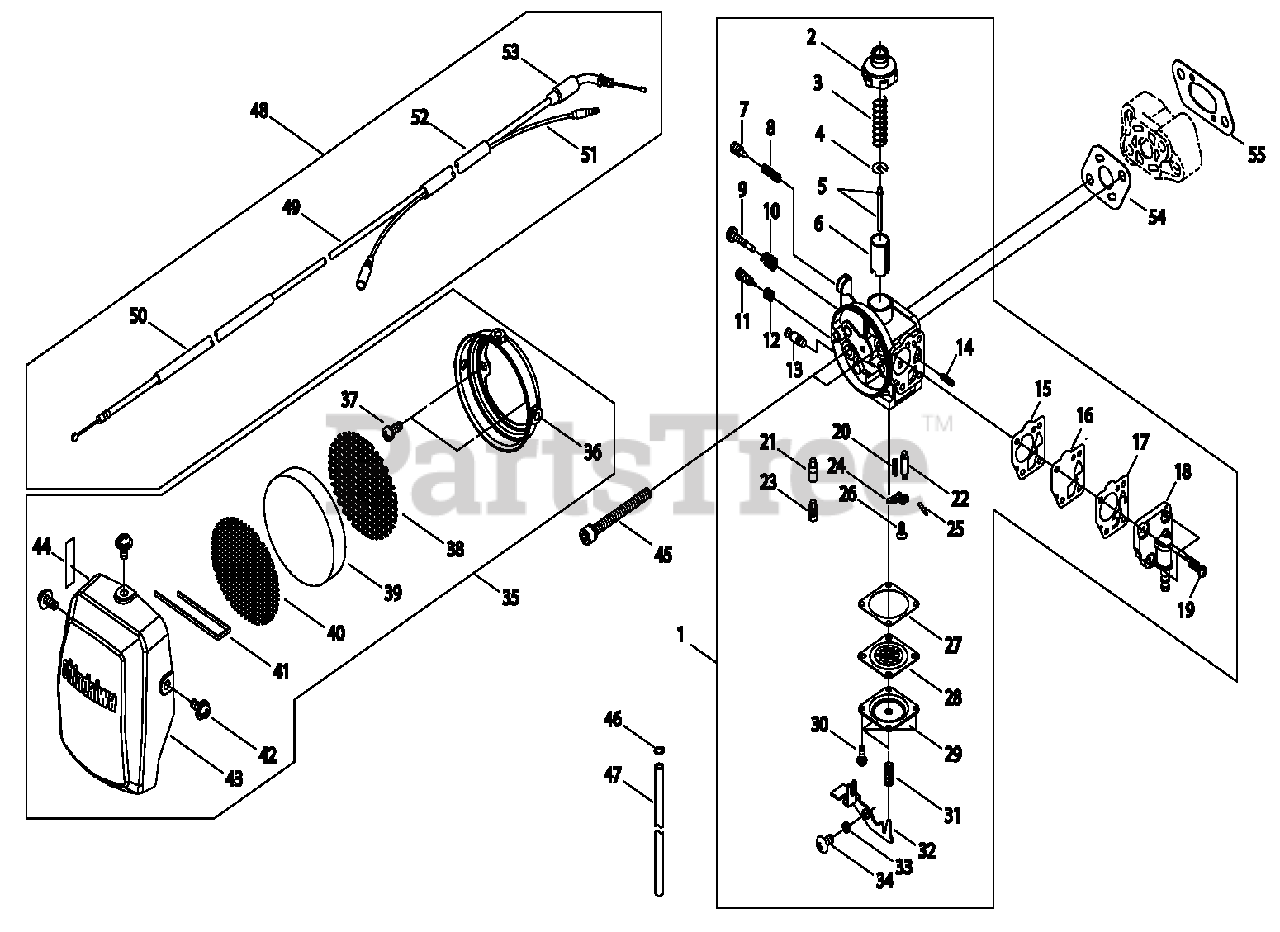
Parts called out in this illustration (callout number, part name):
1	CARBURETOR
2	THROTTLE CAP
3	SPRING
4	SEAT, SPRING
5	NEEDLE
6	VALVE, THROTTLE
7	SCREW, SLOW AIR
8	SPRING
9	SCREW, IDLE ADJUST
10	SPRING
11	SCREW, ADJUST
12	SPRING, ADJUST
13	VALVE, OVERFLOW
14	SPRING
15	GASKET, METERING
16	DIAPHRAGM, METERING
17	VALVE, PUMP
18	BODY, PUMP
19	SCREW
20	SPRING
21	JET
22	VALVE, INLET NEEDLE
23	HOLDER, JET
24	LEVER, METERING
25	PIN, METERING LEVER
26	SCREW, METERING LEVER PIN
27	GASKET
28	DIAPHRAGM, METERING
29	COVER, DIAPHRAGM
30	SCREW
31	SPRING
32	LEVER, TICKLER
33	COLLAR
34	SCREW
35	AIR CLEANER ASSY
36	CASE, AIR FILTER
37	SCREW
38	SCREEN - INNER
39	FILTER, AIR - FOAM
40	SCREEN - OUTER
41	CLIP
42	SCREW
43	COVER, AIR FILTER
44	LABEL - CHOKE
45	SCREW - 5X50
46	CLIP - 6
47	PIPE
48	CONTROL CABLE ASSY
49	CABLE, THROTTLE
50	TUBE, PROTECTIVE
51	LEAD
52	TUBE, PROTECTIVE
53	CAP, CABLE
54	GASKET, INTAKE
55	INSULATOR, INTAKE
